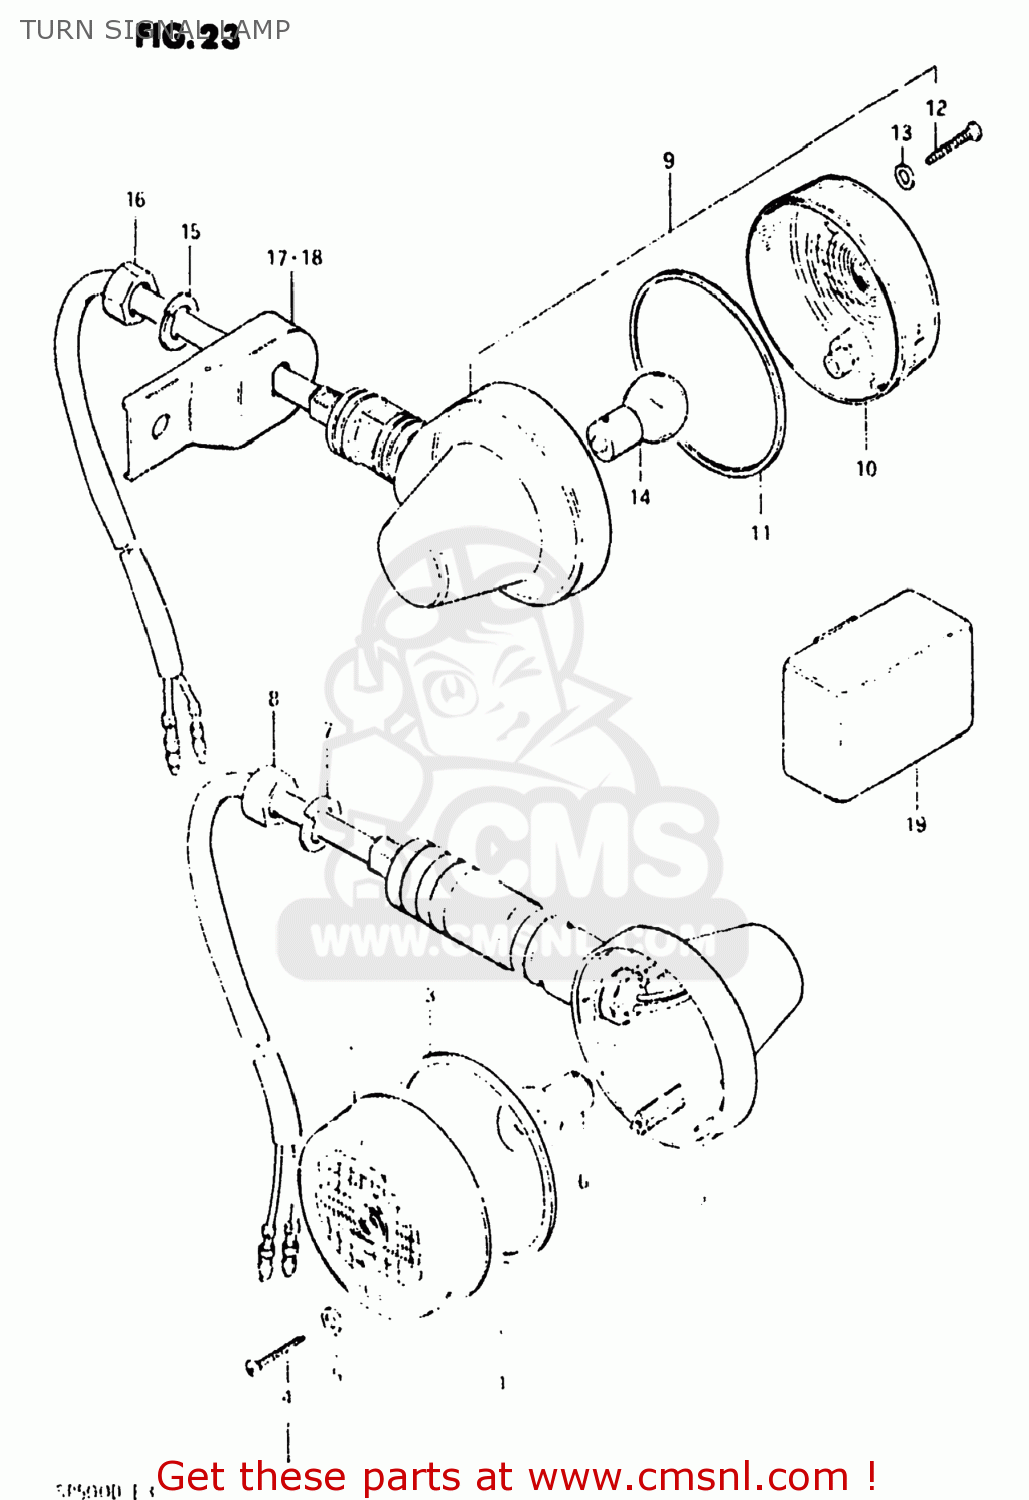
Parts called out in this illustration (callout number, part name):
1	LAMP ASSEMBLY,FRONT TURN SIGNAL
2	LENS
3	GASKET (NAS)
4	SCREW TAPP.
5	GASKET (NAS)
6	BULB(6V17W,STANLEY,A4513A)
7	WASHER,LOCK 12
8	NUT
9	LAMP ASSY,RR TURNSIGNAL
10	LENS
11	GASKET (NAS)
12	SCREW TAPP.
13	GASKET (NAS)
14	BULB(6V17W,STANLEY,A4513A)
15	WASHER,LOCK 12
16	NUT
17	BRACKET,REAR TURN SIGNAL
18	BRACKET,REAR TURN SIGNAL
19	RELAY,TURN SIGNAL
